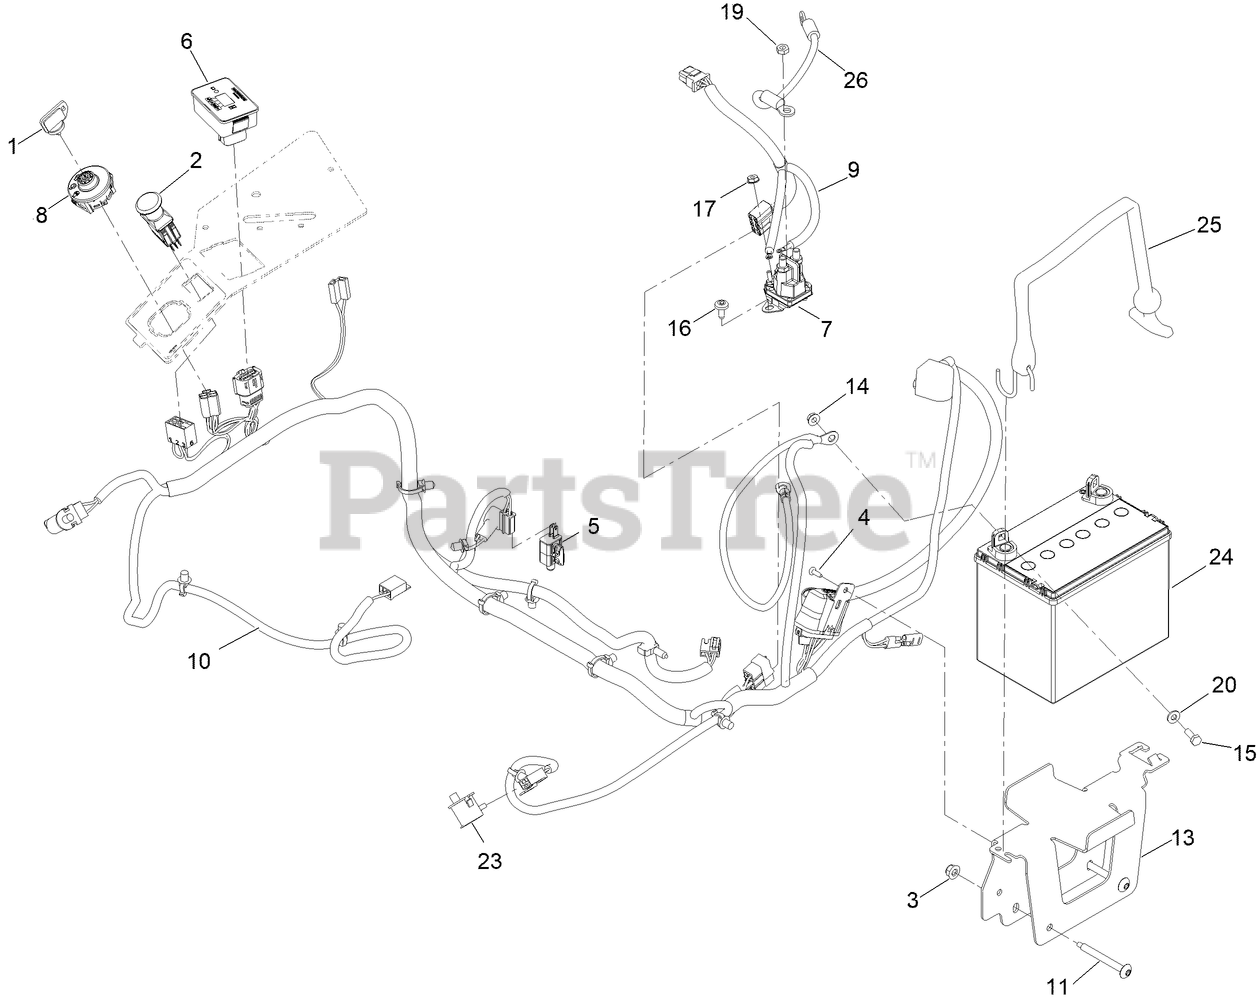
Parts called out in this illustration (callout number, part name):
1	KEY-IGNITION
2	SWITCH-PTO
3	NUT-HF, NI
4	SCREW-FORMING, THREAD
5	SWITCH
6	MODULE ASM
7	SOLENOID
8	SWITCH-IGNITION
9	ADAPTER-HARNESS, WIRE
10	HARNESS-WIRE
11	SCREW-TORX
13	TRAY-BATTERY
14	NUT-HF
15	SCREW-HH
16	SCREW-TORX
17	NUT-KEPS
19	NUT-JAM
20	WASHER-FLAT
23	SWITCH-BAIL
24	BATTERY - WET (300 CCA, 12 V)
25	STRAP, BUNGEE
26	CABLE-BATTERY, POSITIVE
